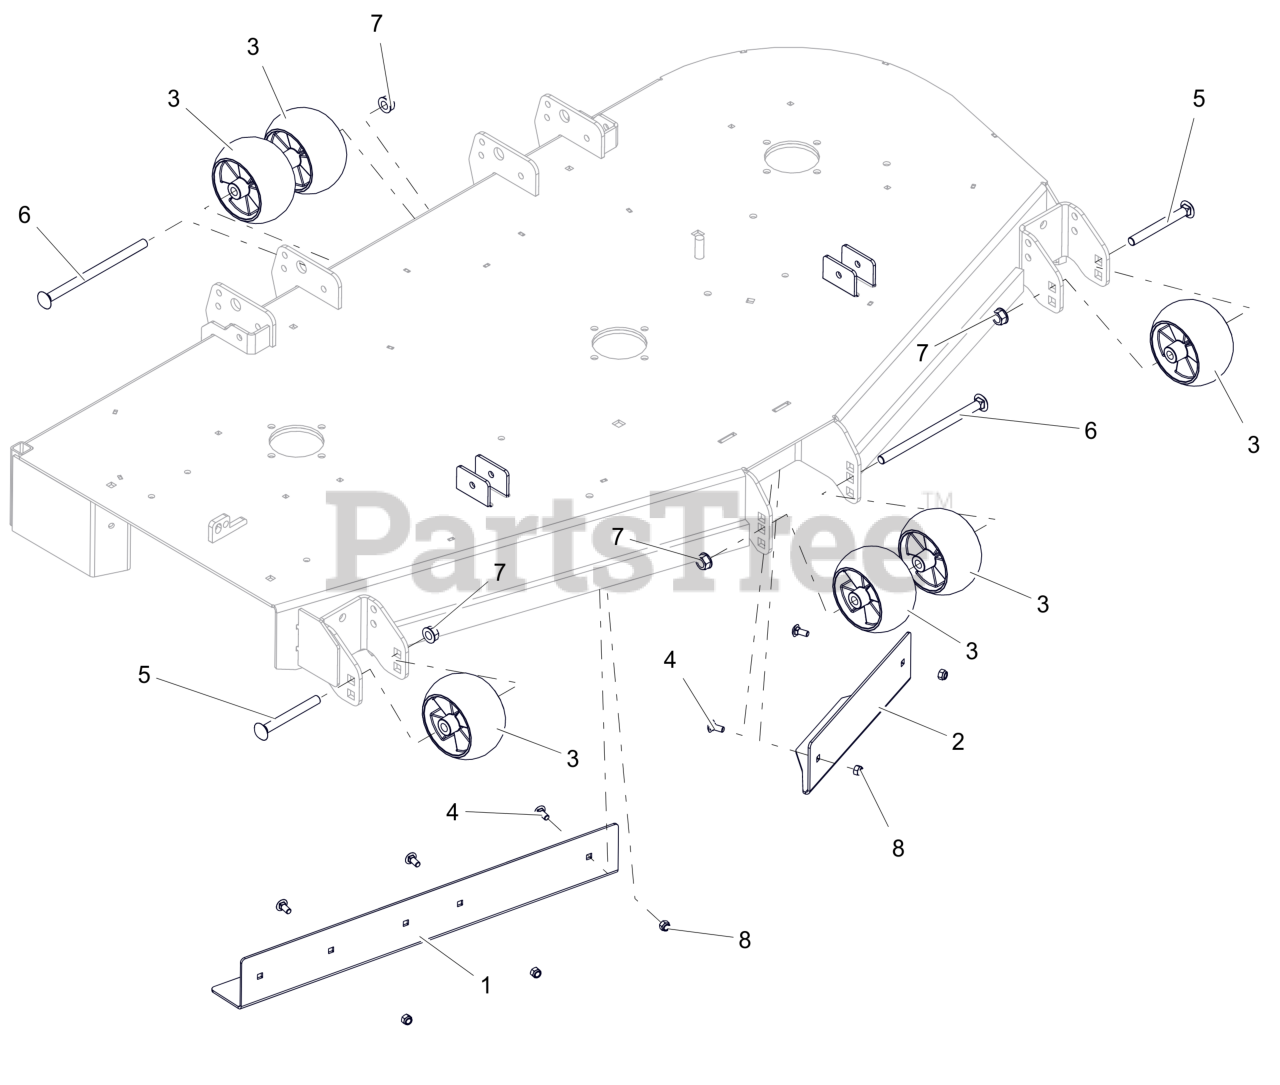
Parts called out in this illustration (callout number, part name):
1	BAFFLE, 60" RH VACUUM (RED)
2	BAFFLE, 60" LH VACUUM (RED)
3	WHEEL, ANTI SCALP - 5X3 CTR W/RIBS
4	BLT,RHSN .31-18X.75 G5 ZCC
5	BLT,RHNS .50-13X4.50 G5 ZCC NS
6	BLT,RHSN .50-13X8.00 G5 ZCC NS
7	NUT-LK-CTR-FLG .500-13 GG ZCC
8	NUT,NYL .31-18 G5 ZCC
